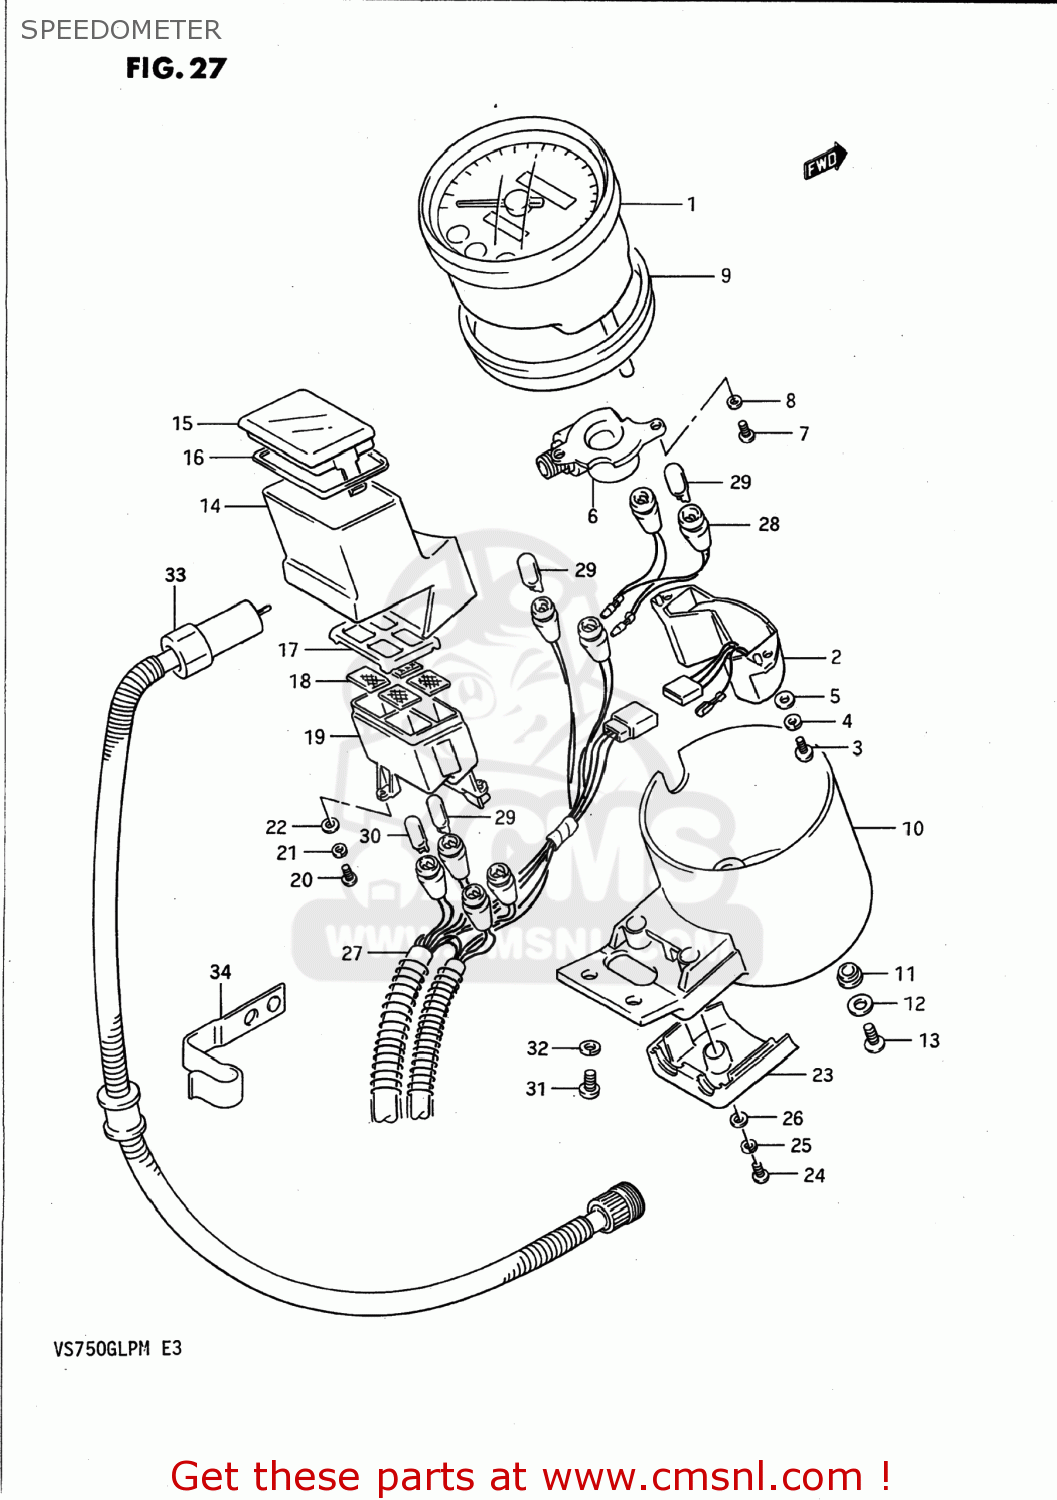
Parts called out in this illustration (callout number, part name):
1	METER,SPEEDOMETER
2	UNIT,WATER TEMP
3	SCREW
4	LOCK WASHER
5	WASHER 3.3X8X0
6	BOX,METER GEAR
7	SCREW 4X10
8	WASHER,LOCK 4M
9	CUSHION
10	COVER,METER
11	CUSHION,METER
12	WASHER
13	SCREW
14	BOX,PILOT
15	LENS,PILOT BOX
16	CUSHION
17	PLATE,PILOT LENS
18	LENS SET
19	CASE,PILOT LAMP
20	SCREW
21	LOCK WASHER
22	WASHER 3.3X8X0
23	COVER,PILOT BOX
24	SCREW
25	WASHER,LOCK 4M
26	WASHER 4MM
27	SOCKET,METER
28	SOCKET
29	BULB(12V3W,T6.5)
30	BULB(12V1.7W,T6.5)
31	SCREW
32	WASHER,LOCK
33	CABLE ASSY,SPEEDOMETER
34	CLAMP,SPEEDOMETER CABLE
